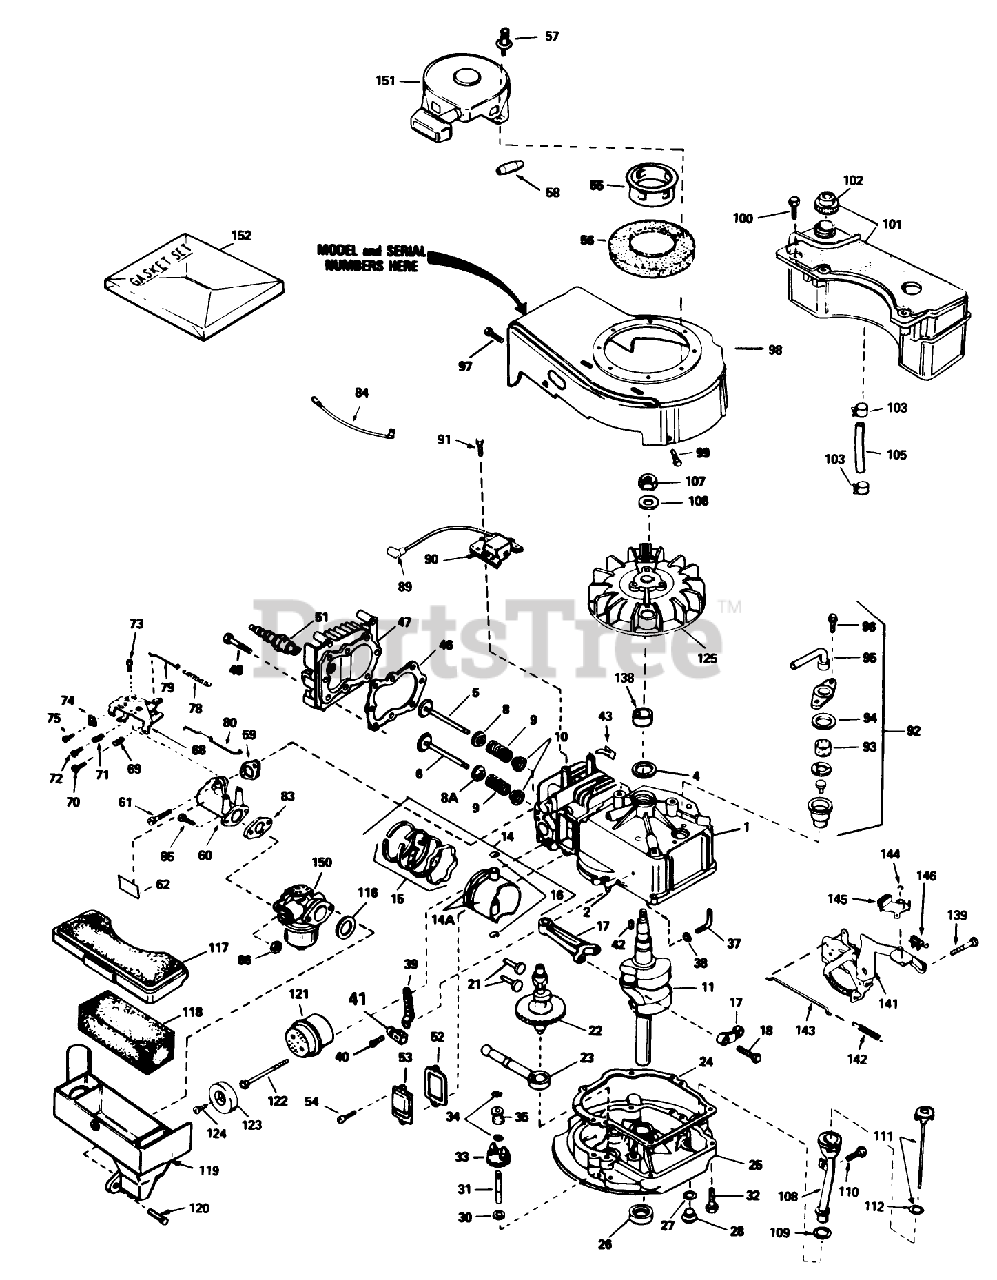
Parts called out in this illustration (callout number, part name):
1	Cylinder Assy. (Incl. #24)
2	Pin-Dowel
4	Seal-Oil
5	Valve, Intake (Std.) (Incl. Ref. #40)
5	Valve, Intake (1/32" oversize)(Incl. No. 40)
6	Valve, Exhaust (Std.)(Incl. No. 40)
6	Valve, Intake (1/32" oversize)(Incl. No. 40)
8	Seal Assy., Intake
8A	Cap-Upper Valve Spring
9	Spring-Valve
10	Cap-Valve, Spring
11	Crankshaft
14	Piston, Pin Ring Assy. (Std.) (Incl. Ref. #13A, 14 15)
14	Piston, Pin Ring Assy. (.010 oversize) (Incl. Ref. #13A, 14 15)
14	Piston, Pin Ring Assy. (.020 oversize) (Incl. Ref. #13A, 14 15)
14A	Piston Pin Assy. (Incl . Ref. . #14) (Std.)
14A	Piston Pin Assy. (Incl. Ref. #14) (.010 Oversize)
14A	Piston Pin Assy. (.020 oversize) (Incl. Ref. #14)
15	Ring Set (Std.)
15	Ring Set (.020" OS)
15	Ring Set (.010" OS)
16	Ring-Retaining, Piston Pin
17	Rod Assy., Connecting (Incl. Ref. #17)
18	Bolt-Rod, Connecting
21	Lifter-Valve
22	Camshaft(Mech.Comp. Release)
23	Oil Pump ASM
24	Gasket
25	Flange Assy.-Mounting (Incl. Ref. #26, 27, 28 31)
26	Seal Oil
27	Gasket-Oil Drain
28	Plug Oil Drain
30	Washer-Flat
31	Shaft-Governor
32	Screw (1/4-20 x 1-1/4)
33	Governor Gear ASM
34	Ring-Retaining
35	Spool-Governor
37	Rod, Governor (Incl. No. 36)
38	Washer-Flat
39	Governor Lever
40	Screw
41	Clamp-Lever, Governor
42	Key-Flywheel
43	Clip-Wire
46	63573 GIL 42 SNWTHW
47	Head-Cylinder
48	Screw (5/16-18x1-1/2)
51	Plug, Spark (Autolite 458, Champion J-19LM or equiv.)
52	Gasket-Breather
53	Cover-Valve
54	Screw
55	Cup-Starter
56	Screen-Starter
57	Pop Rivet (Can be purchased locally)
58	Retainer-Starter Rope
59	Gasket-Intake
60	Pipe-Intake (Incl. Ref. #59)
61	Screw (1/4-20 x 1)
62	Decal-Primer
68	Control Assy.-Remote Speed (Incl. Ref. #69 thru 72 76)
69	61709/GIL1515A/95-5
70	Screw
71	Spring-Compression
72	Screw
73	Screw (10-24 x 9/16)
74	Conduit
75	Screw (10-32 x 3/8)
78	Spring Governor
79	2035A67 ADD.ASSEMBL
80	Link-Throttle
83	Gasket
84	Ground Wire
86	Nut and Lock Washer (1/4-28)
89	Cover-Spark Plug
90	Solid State
91	Screw
92	Breather Assy. (Incl. Ref. #46 thru 51)
93	Element-Breather
94	Gasket-Breather
95	Tube, Breaker
96	Screw (10-24 x 9/16)
97	Screw (10-24 x 9/16)
98	Housing-Blower
99	Screw (1/4-20 x 1/2)
100	Screw (10-32 x 35/64)
101	Tank Assembly-Fuel (Incl. Ref. #102)
102	Cap-Fuel
103	Clamp-Line, Fuel
105	Line-Fuel
106	Washer-Belleville
107	Nut-Flywheel
108	Tube-Oil Fill
109	Gasket
110	Screw (10-32 x 1/2)
111	Dipstick-Oil (Incl. Ref. #112)
112	O-Ring
116	Gasket-Cleaner, Air
117	Cover Air Cleaner
118	Filter-Air Cleaner
119	Body Air cleaner
120	Screw
121	B Muffler (Incl. Ref. #122)
122	Screw
123	Cover-Muffler
124	Screw
125	Flywheel
138	Spacer
139	Screw (1/4-20 x 3/8)
141	Bracket Assy.
142	Spring-Extension
143	Link-Control
144	Ring-Retaining
145	Lever-Brake
146	Terminal
150	Carburetor (Incl. Ref. #83)
151	tarter-Rewind
152	Gasket Set
